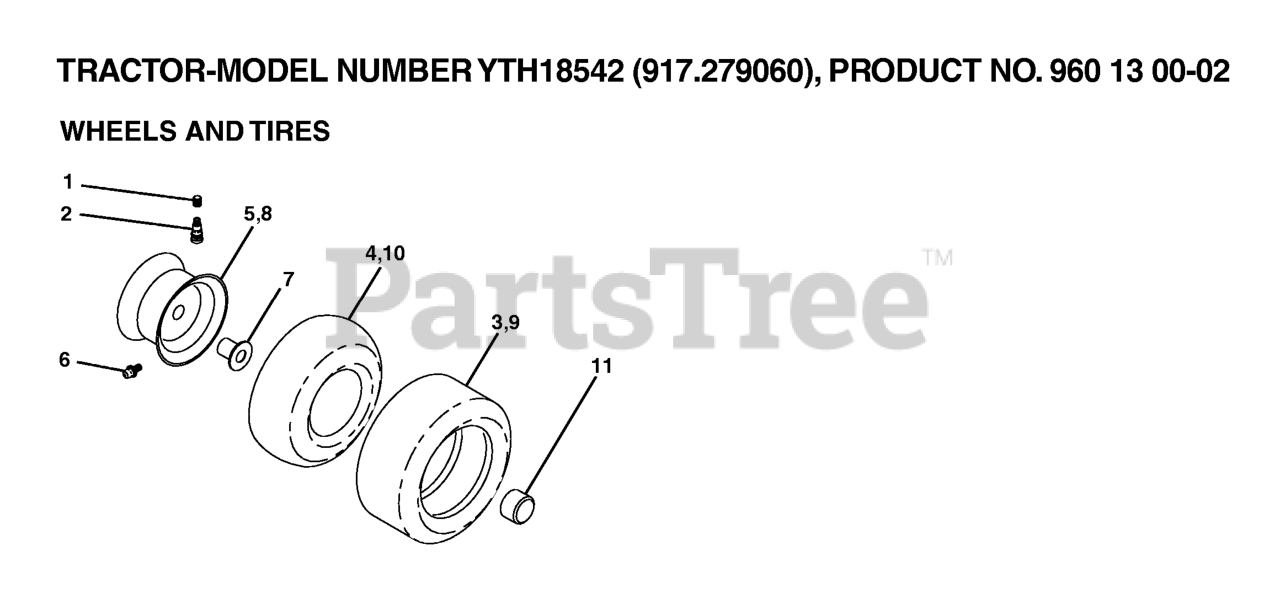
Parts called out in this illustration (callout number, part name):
2	VALVE STEM LT
3	TIRE HEAVY DUTY
4	TUBE.5.3/4.5/6
5	RIM ASM 6" FRONT SILVER
6	FITTING LT
7	BEARING T
8	RIM ASM 8" REAR SILVER
9	TIRE.20X8-8.TURF.SAVER
10	TUBE
11	CAP, AXLE BLK
